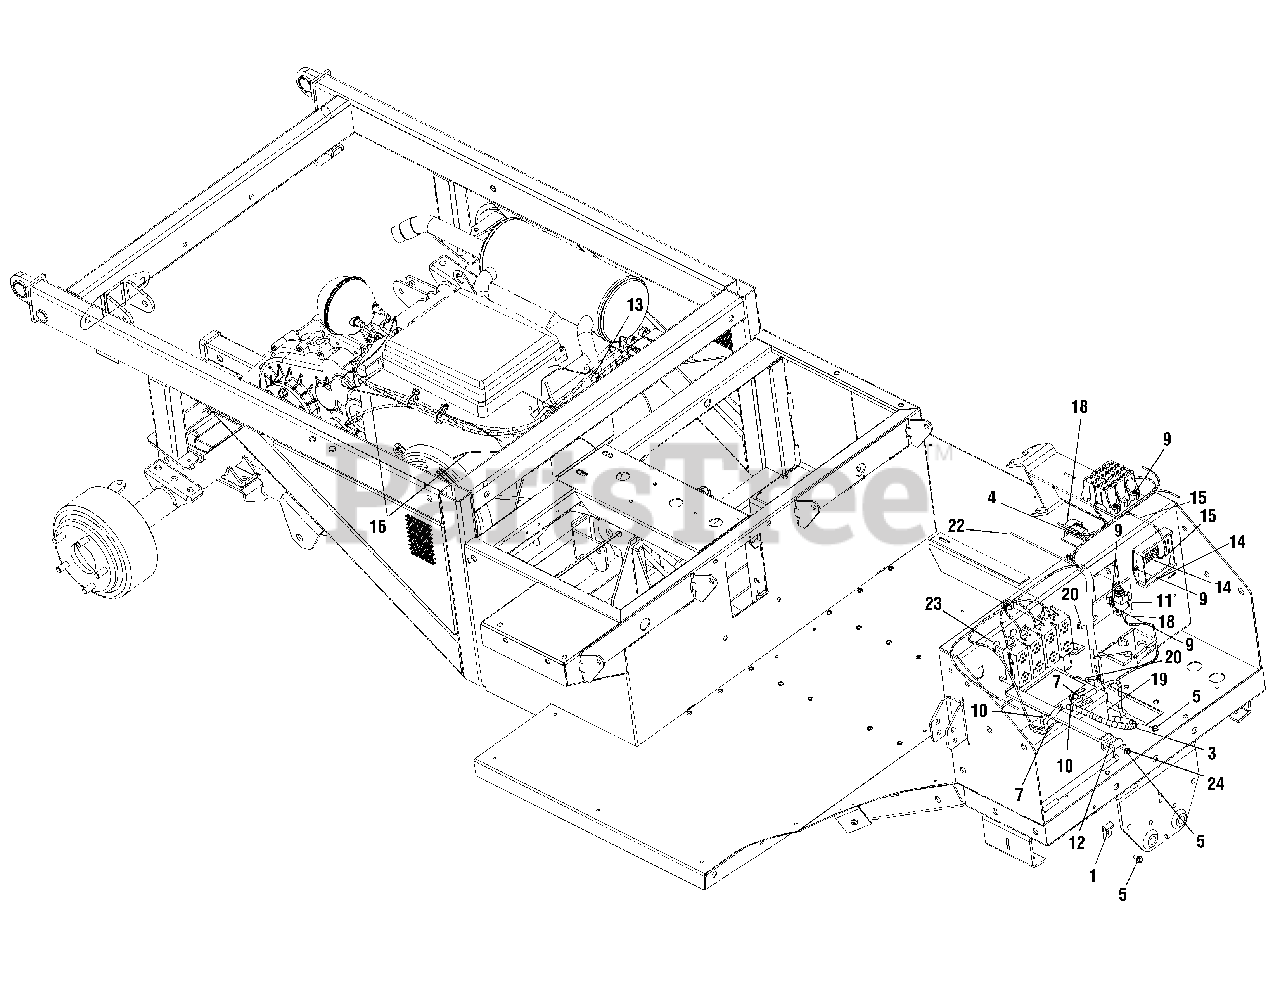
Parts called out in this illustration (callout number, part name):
1	Bracket, Retainer Hook
2	Harness Assembly, Starter
3	Harness Assembly, Motor Ground
4	Screw, 1/4-20 x .50
5	Screw, Self-tapping, 1/4-20 x 0.500
6	Screw, Self-tapping, 5/16-18 x .50
7	Screw, Hex Carriage, 1/4-20 x .75
8	Screw, Self-tapping, 1/4-20 x 1.000
9	Screw, #10-24 x 0.75
10	Nut, Hex Sems, 1/4-20
11	Cover, Protective
12	Strap, Battery
13	Cable Tie, 3/16 x .05 x 7.4
14	Control, Shaft
15	Harness, Utility Main
16	Harness, Motor Kohler
17	Control, Reverse
18	Switch
19	Battery
20	Cable Tie, .19 x 8.39 Tree Mount
21	Lock Washer, 1/4
22	Hourmeater Jumper Harness
23	Pop Rivet.188
24	Lock Washer 1/4 exterbak
25	Fuel Line Hose
